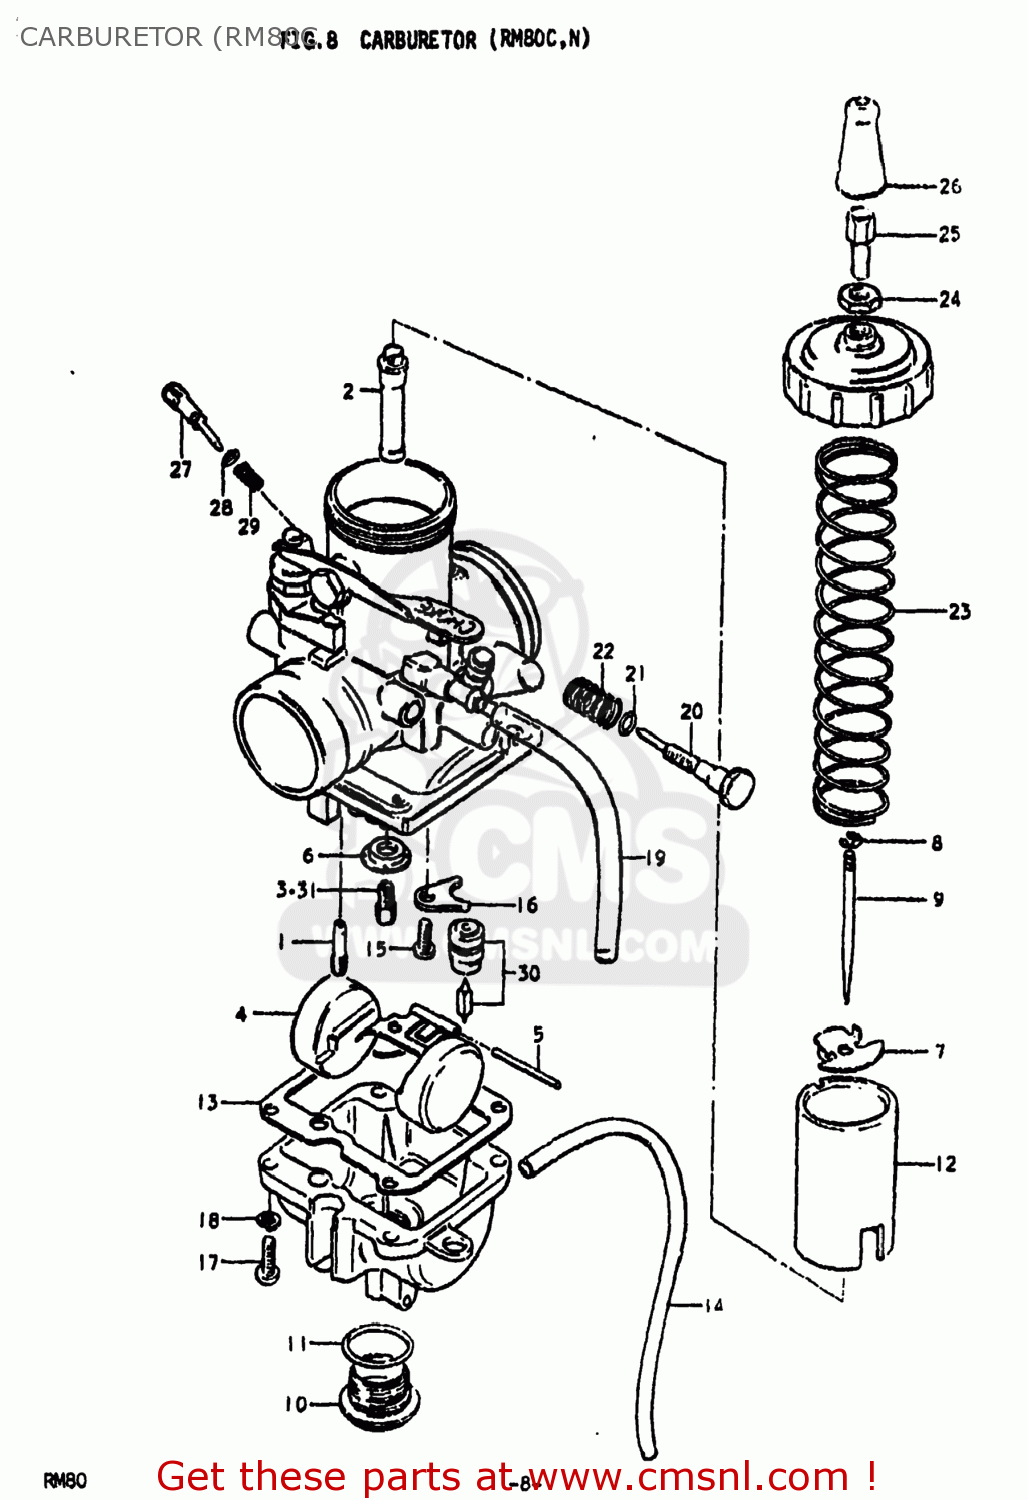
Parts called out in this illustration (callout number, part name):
0	CARBURETOR ASSEMBLY
1	JET,PILOT(45)
2	JET,NEEDLE
3	JET
4	FLOAT
5	PIN,FLOAT
6	RING
7	PLATE,THROTTLE VALVE
8	CLIP
9	NEEDLE,JET(5DP39-4)
10	PLUG
11	O RING
12	VALVE,THROTTLE
13	GASKET,FLOAT CAHMBER (NAS)
14	HOSE
15	SCREW
16	PLATE
17	SCREW
18	LOCK WASHER
19	HOSE
20	ADJUSTER
21	O-RING
22	SPRING
23	SPRING,THROTTLE VALVE
24	NUT
25	ADJUSTER,CABLE
26	CAP
27	SCREW,PILOT AIR ADJUSTING
28	O RING
29	SPRING
30	VALVE ASSY,NEEDLE
31	JET
